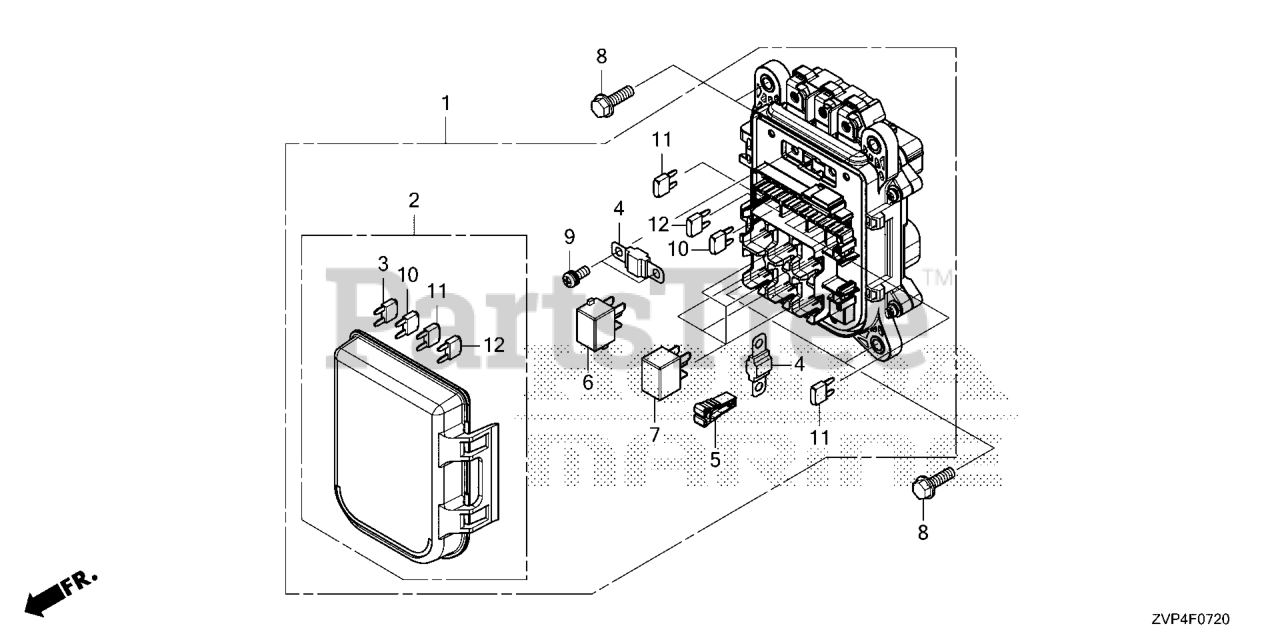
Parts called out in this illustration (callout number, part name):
1	BOX ASSY., JUNCTION
2	COVER COMP, FUSE
3	FUSE, BLADE (3A)
4	FUSE, BLOCK (200A)
5	PULLER, MINI FUSE
6	RELAY ASSY., FUEL PUMP (DENSO)
7	RELAY ASSY., POWER (12V-20A) (MICRO ISO 4P)
8	BOLT, FLANGE (6X20)
9	SCREW-WASHER (5X15)
10	FUSE, MINI (7.5A)
11	FUSE, MINI (15A)
12	FUSE, MINI (30A)
